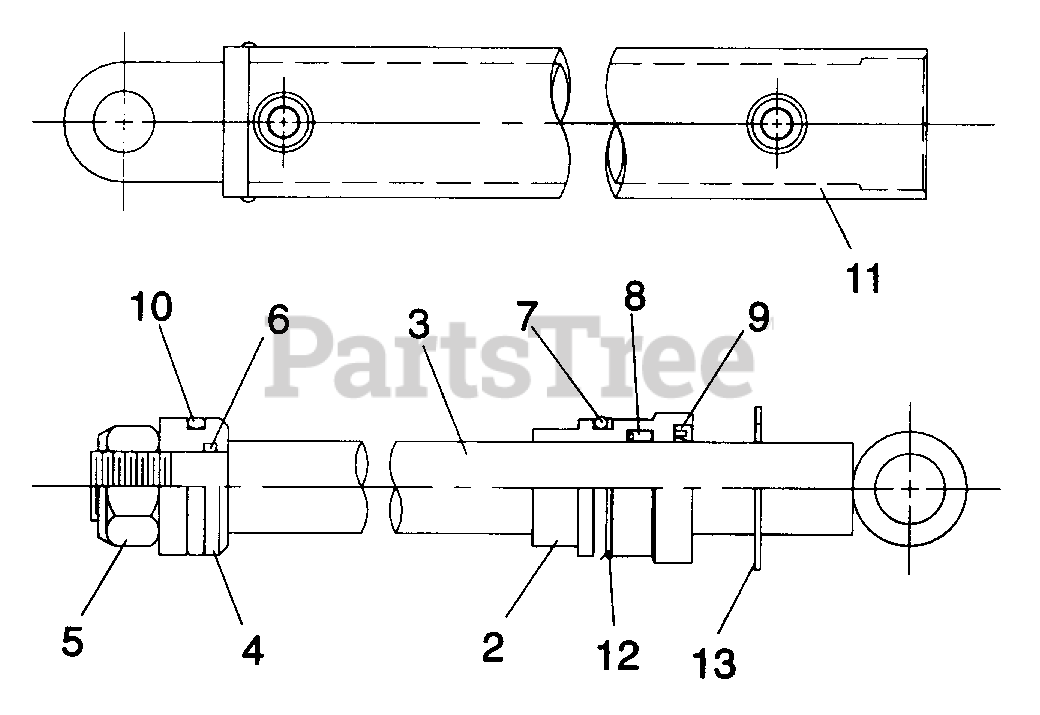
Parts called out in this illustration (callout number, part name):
2	Seal retainer
3	Rod
4	Piston
5	Locknut
6	O-Ring
7	O-Ring
8	U-Ring
9	Wiper ring
10	Piston seal
11	Tube
12	Back-up ring
13	Snap ring
